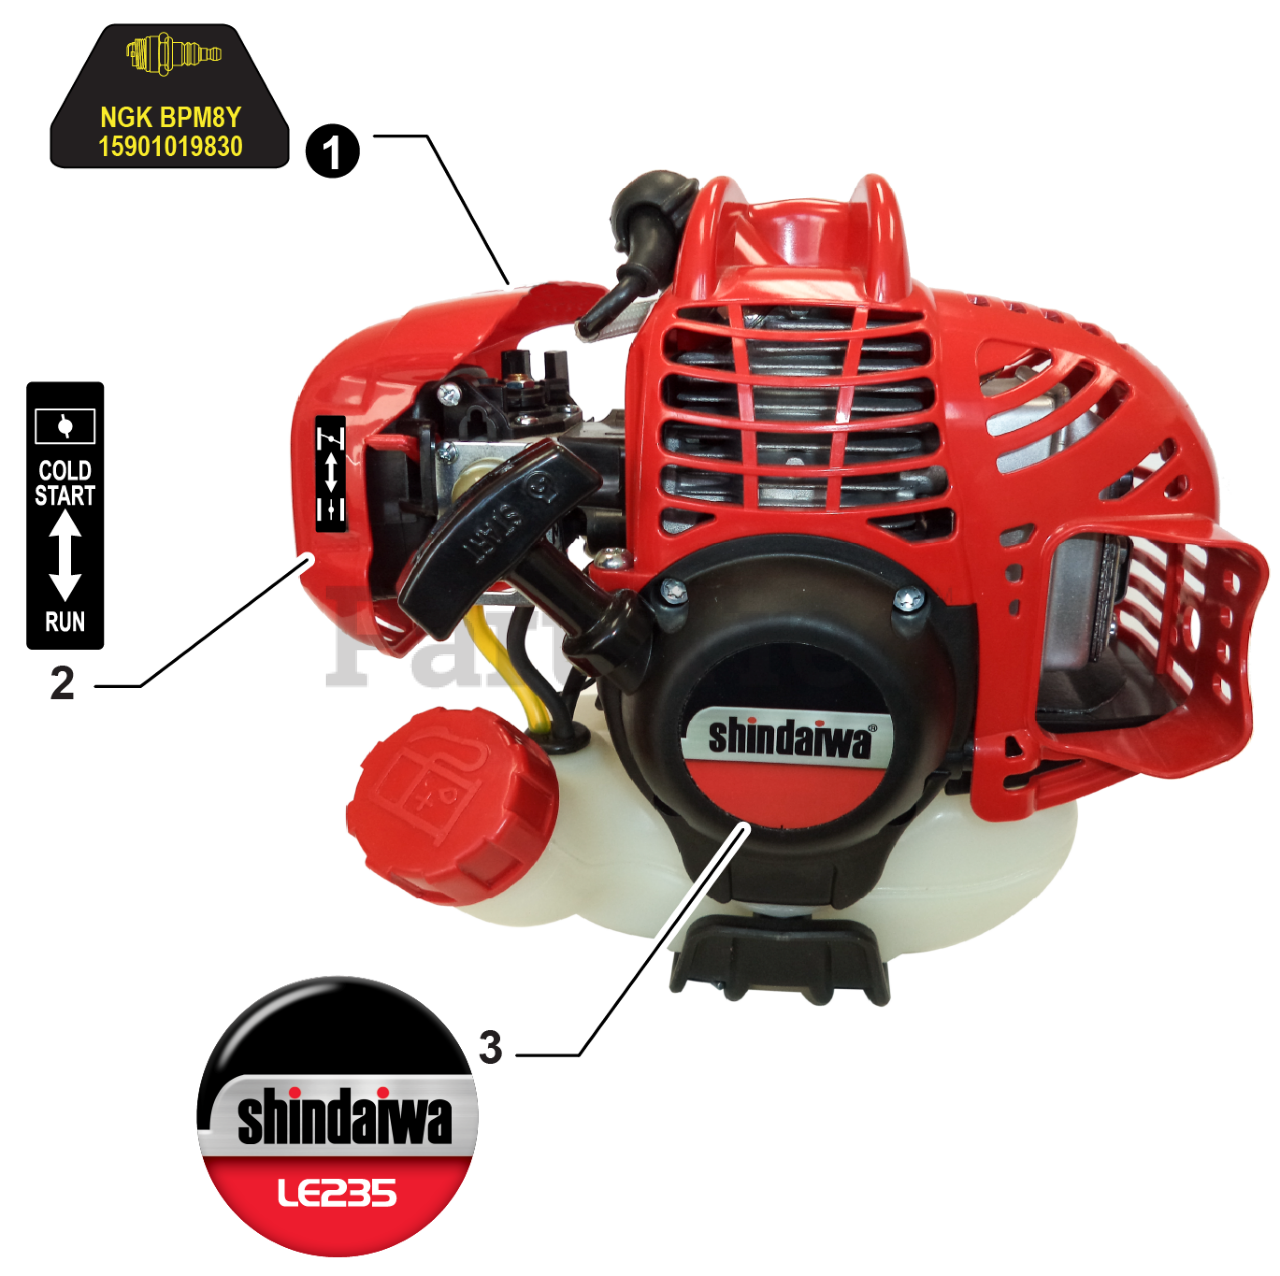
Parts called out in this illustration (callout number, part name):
1	LABEL - SPARK PLUG - BPM8Y
2	LABEL - CHOKE
3	LABEL - SHINDAIWA - LE235
